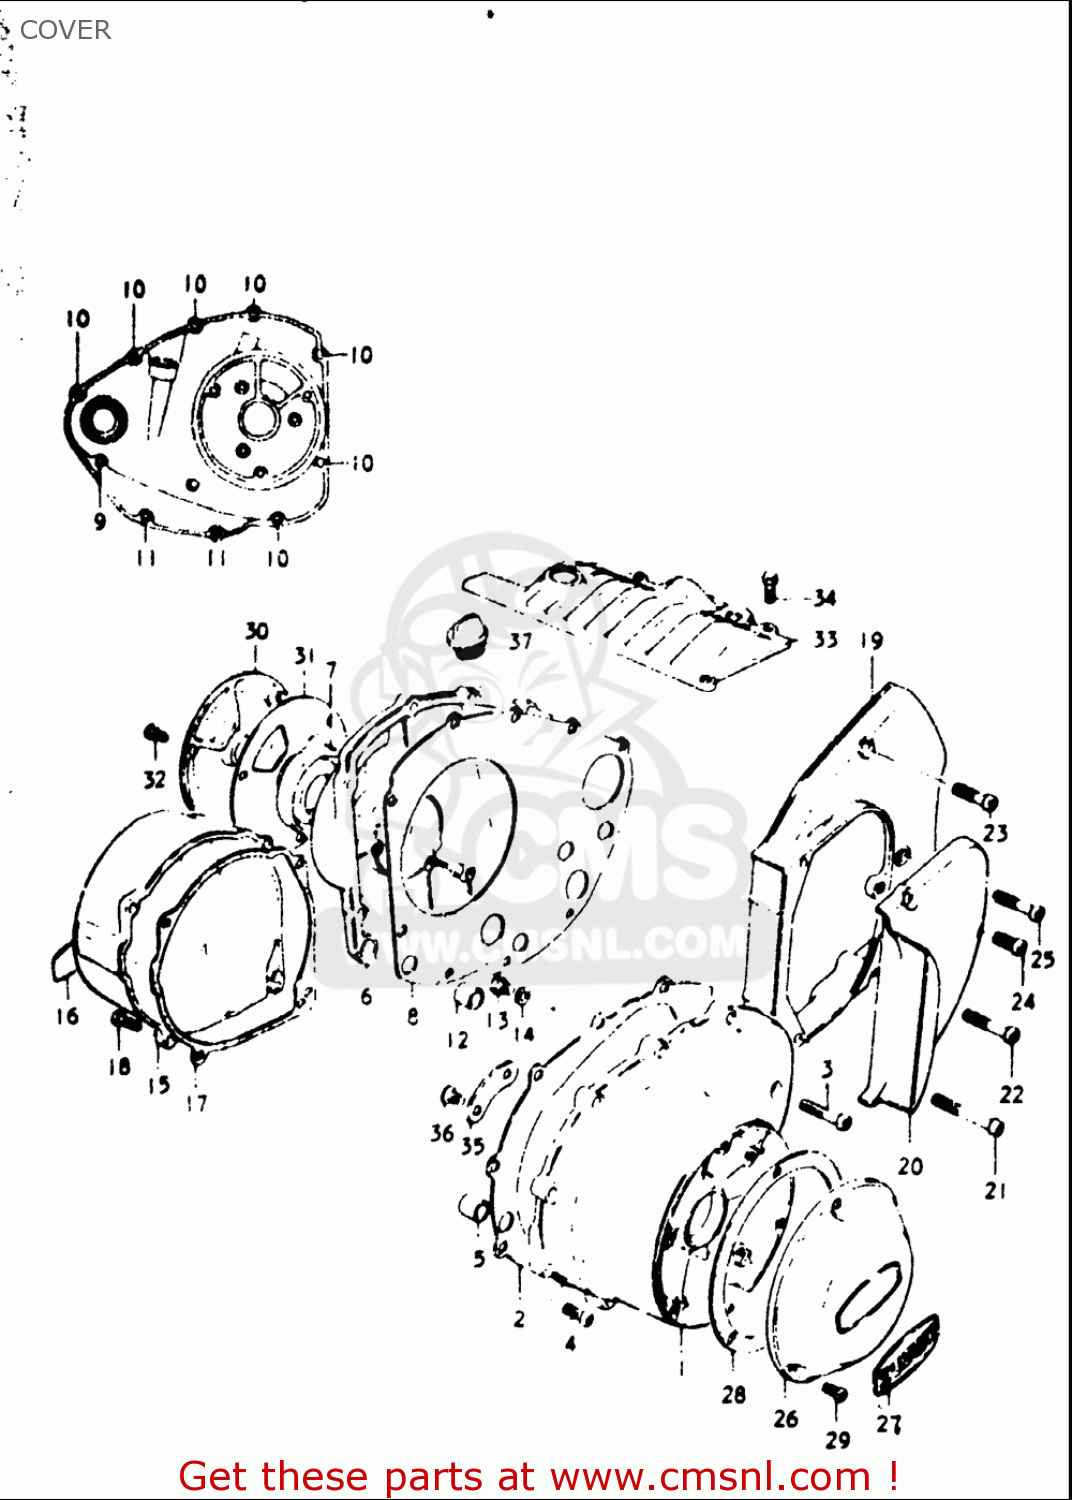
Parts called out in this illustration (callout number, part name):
2	GASKET GEAR COVER (NAS)
3	SCREW
4	SCREW
5	PIN
7	SEAL,OIL(25X34X6)
8	GASKET,CLUTCH COVER (NAS)
9	SCREW
10	SCREW
11	SCREW
12	PIN
13	SCREW(6X10)
14	GASKET(6.2X11X1) (NAS)
15	COVER,GENERATOR
16	EMBLEM,GENERATOR COVER
17	GASKET,GENERATOR COVER (NAS)
18	SCREW
21	SCREW
22	SCREW
23	SCREW
24	SCREW
25	SCREW
26	CAP SET,CONTACT BREAKER
27	EMBLEM,GENERATOR COVER
28	GASKET,CONTACT BREAKER CAP (NAS)
29	SCREW
31	GASKET,CL RLSE ADJ CAP (NAS)
32	SCREW
34	BOLT
36	SCREW
37	PLUG
